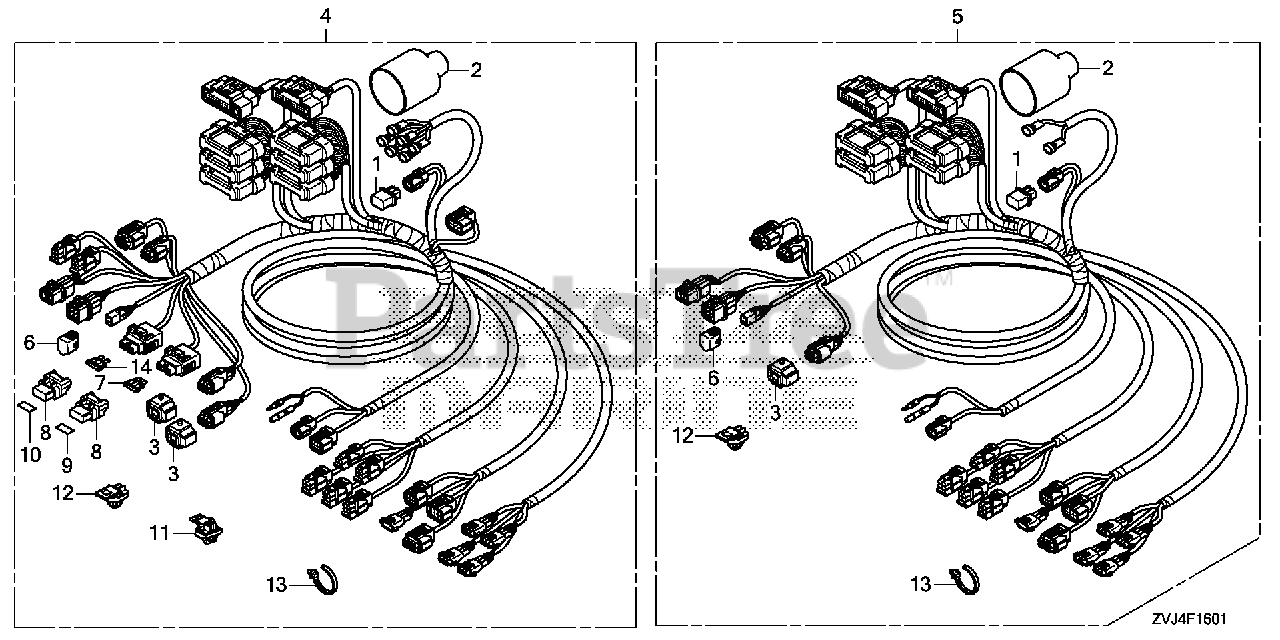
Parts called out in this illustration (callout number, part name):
1	TERMINATOR ASSY.
2	COVER, CONNECTOR
3	SUSPENSION, CONNECTOR
4	CABLE ASSY., REMOTE CONTROL (MAIN)
6	CAP, DUMMY (WPC 4P 090 M) (RED)
7	FUSE, BLADE (3A)
8	COVER ASSY., FUSE
9	LABEL, FUSE (3A)
10	LABEL, FUSE (5A)
11	CLIP, CONNECTOR (DARK BLUE)
12	CLIP, CONNECTOR (DARK BROWN)
13	CLIP, HARNESS BAND (145MM) (BLACK)
14	FUSE, MINI (5A)
